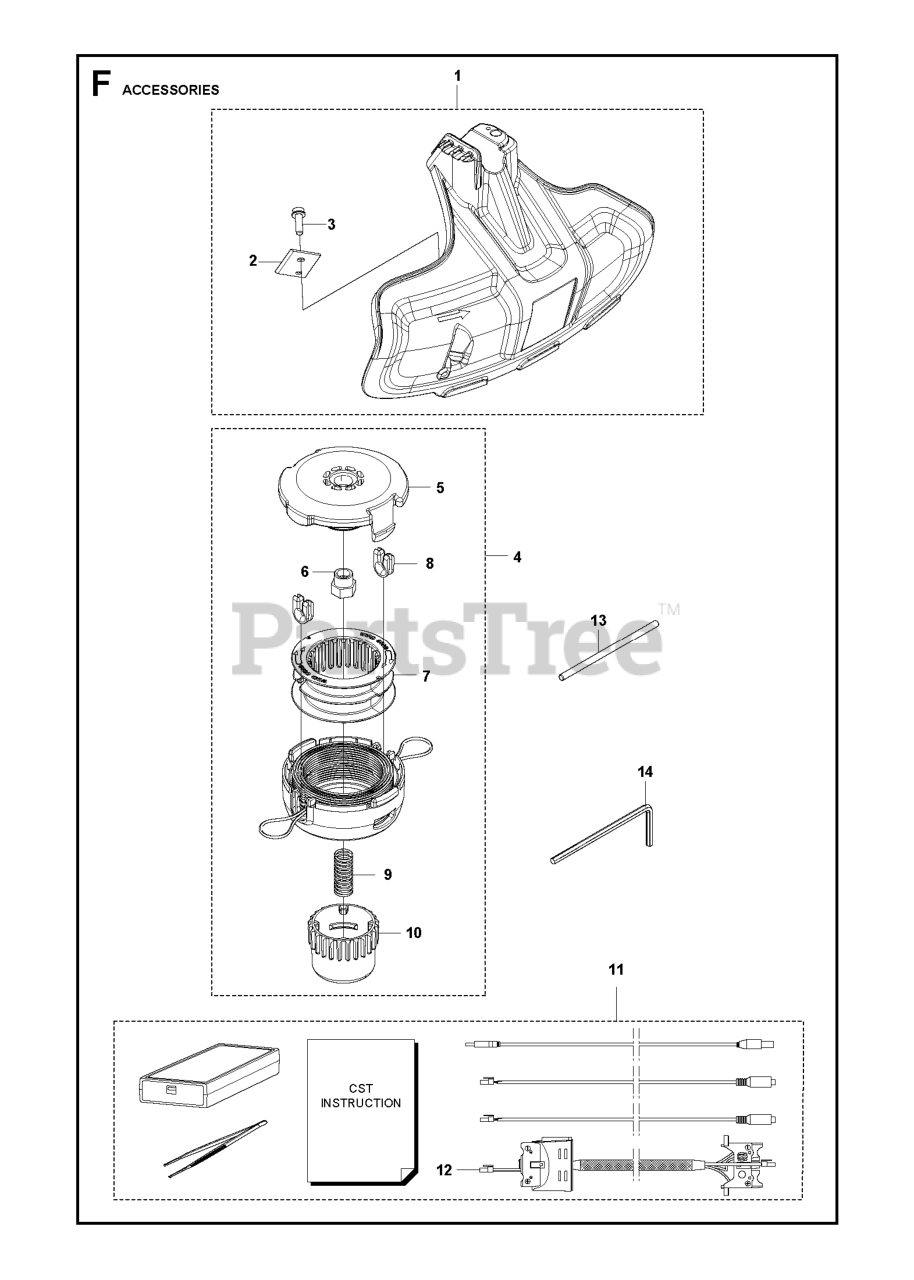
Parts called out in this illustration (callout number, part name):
1	Trimmer Guard
3	SCREW ITXSCFT PW4.8X16 T27 CH
4	TRIMMER HEADS
5	HOUSING
6	ADAPTER M10 X 1.25L
7	SPOOL
8	EYELET
9	SPRING
10	KNOB.T35
11	DIAGNOSTIC TOOL KIT
12	WIRING ASSY
13	LOCKING PIN
